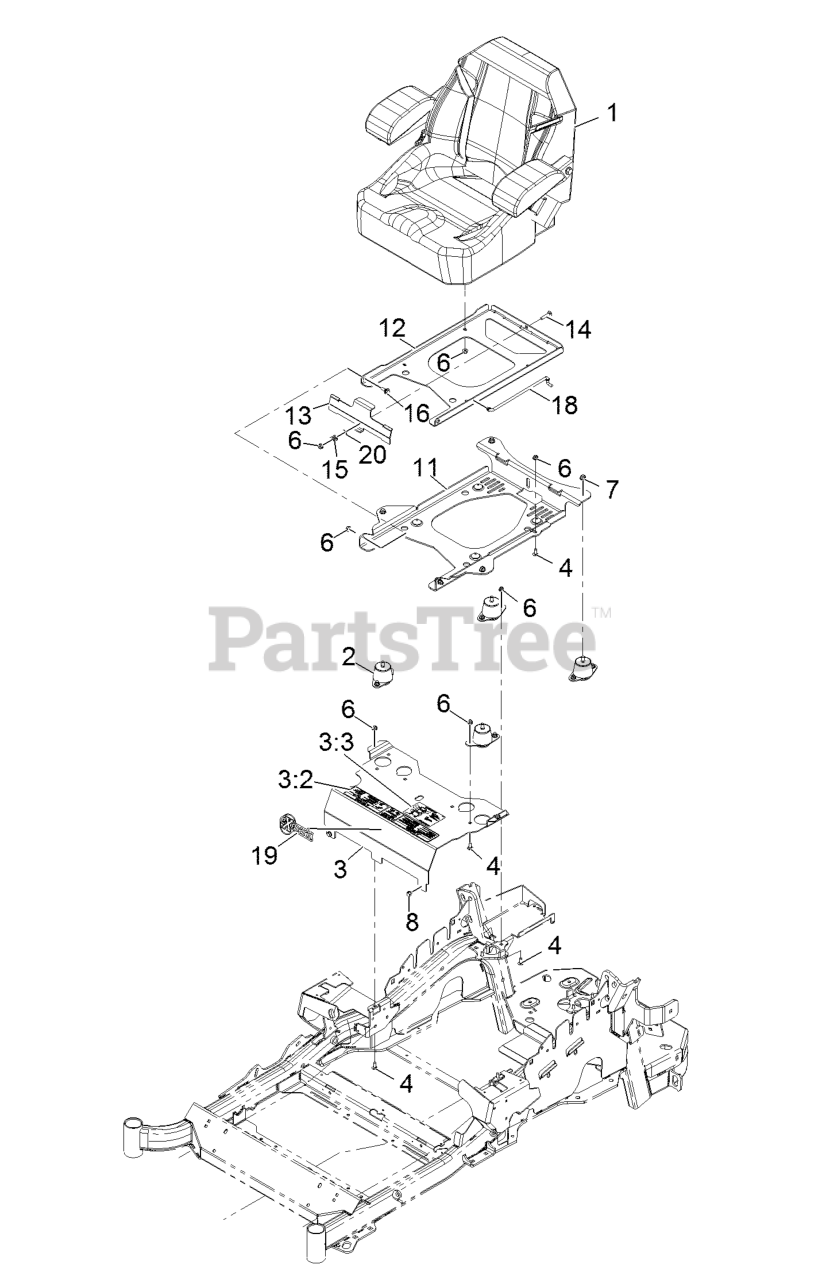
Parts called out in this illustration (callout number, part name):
2	ISOLATOR-SEAT
3	MOUNT-SEAT
3:2	DECAL-CONSOLE
3:3	DECAL-SERVICE AID
4	SCREW-CARR
6	NUT-HF, NI
7	NUT-HF, NI
11	PLATE-TILT, SEAT SUPPORT
12	PLATE-FRAME, SEAT
13	PLATE-LATCH, SEAT
14	BOLT-CARR
15	SPRING-COMPRESSION
16	SCREW-SHOULDER
18	ROD-PROP
20	WASHER-PLAIN
